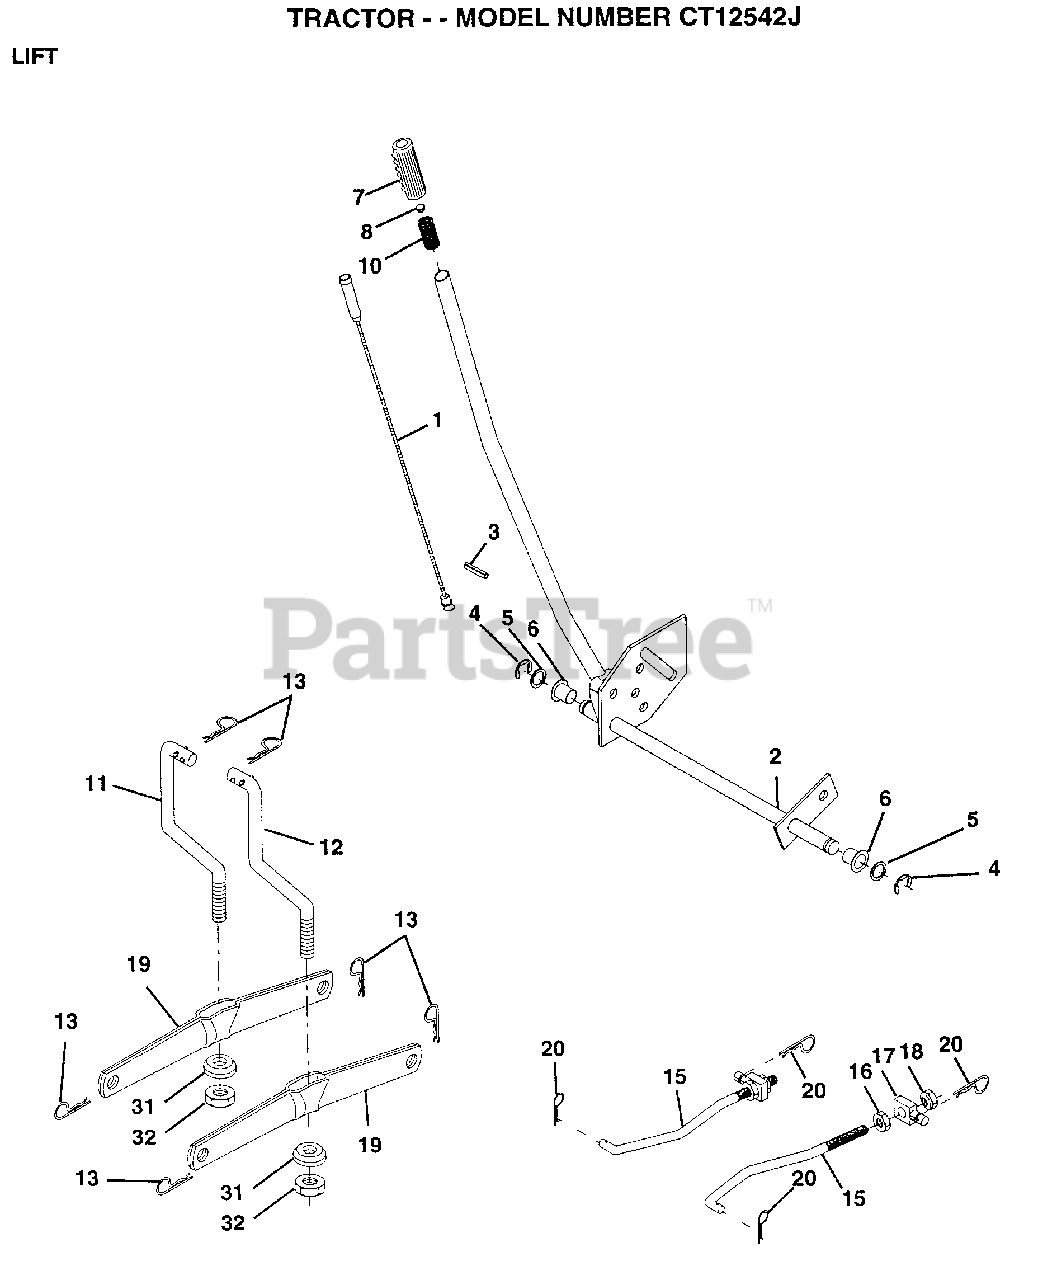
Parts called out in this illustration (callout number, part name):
1	WIRE ASM
2	HANDLE.LIFT.LH.
3	PIN GROOVE
5	WASHER
6	NYLON BEARING
7	GRIP
15	LINK.FRONT
16	NUT
17	TRUNION
18	NUT.LK.W/WSH.1/2.
19	ARM SUSP REAR
20	RETAINER.SPRING
31	BEARING PVT LH
32	NUT.CROWNLOCK.3/8
